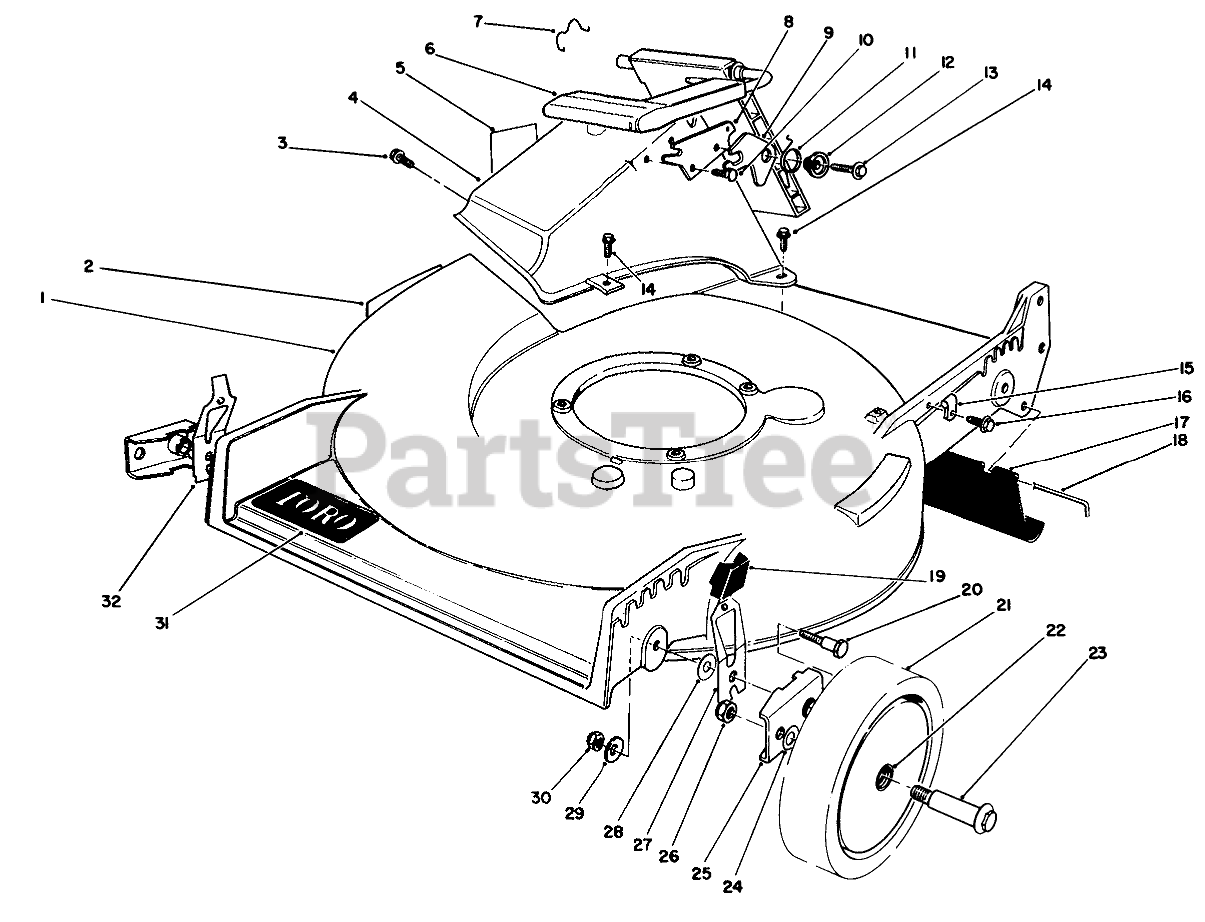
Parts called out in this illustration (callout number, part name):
1	Housing (Incl. Ref. #2)
2	DECAL-DANGER
3	SCREW AND WASHER ASM
4	Tunnel-Discharge (Incl. Ref. #5)
5	DECAL - DANGER
6	Discharge Door Assembly
7	DOOR RET SPRING
8	DOOR LATCH PLATE
9	SAFETY LATCH
10	SCREW-PLASTITE
11	TORSION SPRING
12	DOOR SPACER
13	SCREW-HWH
14	SCREW-HWH
15	CLAMP-CABLE
16	SCREW
17	SHIELD-TRAILING
18	ROD-SHIELD
19	KNOB-ARM
20	PIVOT SCREW
21	Wheel & Tire Assembly (Incl. Ref. #22)
22	BUSHING
23	BOLT-WHEEL
24	WASHER
25	HP PIVOT ARM ASM
26	Nut
27	L. HP SPRING ARM ASM
28	WASHER-PIVOT
29	WASHER-BELLEVILLE
30	NUT-LOCK, NI
31	DECAL
32	R HP SPRING ARM ASM
